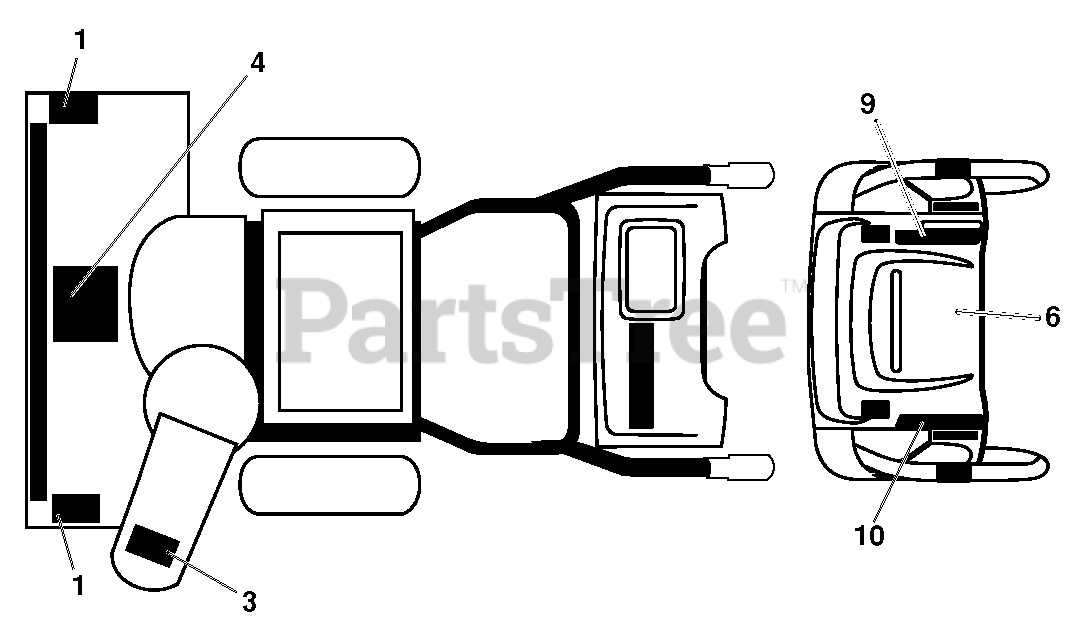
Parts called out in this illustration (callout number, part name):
1	DECAL.SNOWTHR.AUGER
3	Decal, Snow Thrower Chute Safety
4	Decal, Snow Thrower Read Owner's Manual E/F
6	Instruction Panel Decal
9	DECAL.CONS.RT.SPD/LEV/P.WRST
10	DECAL.CONS.LT.SPD/LEV/P.WRST
